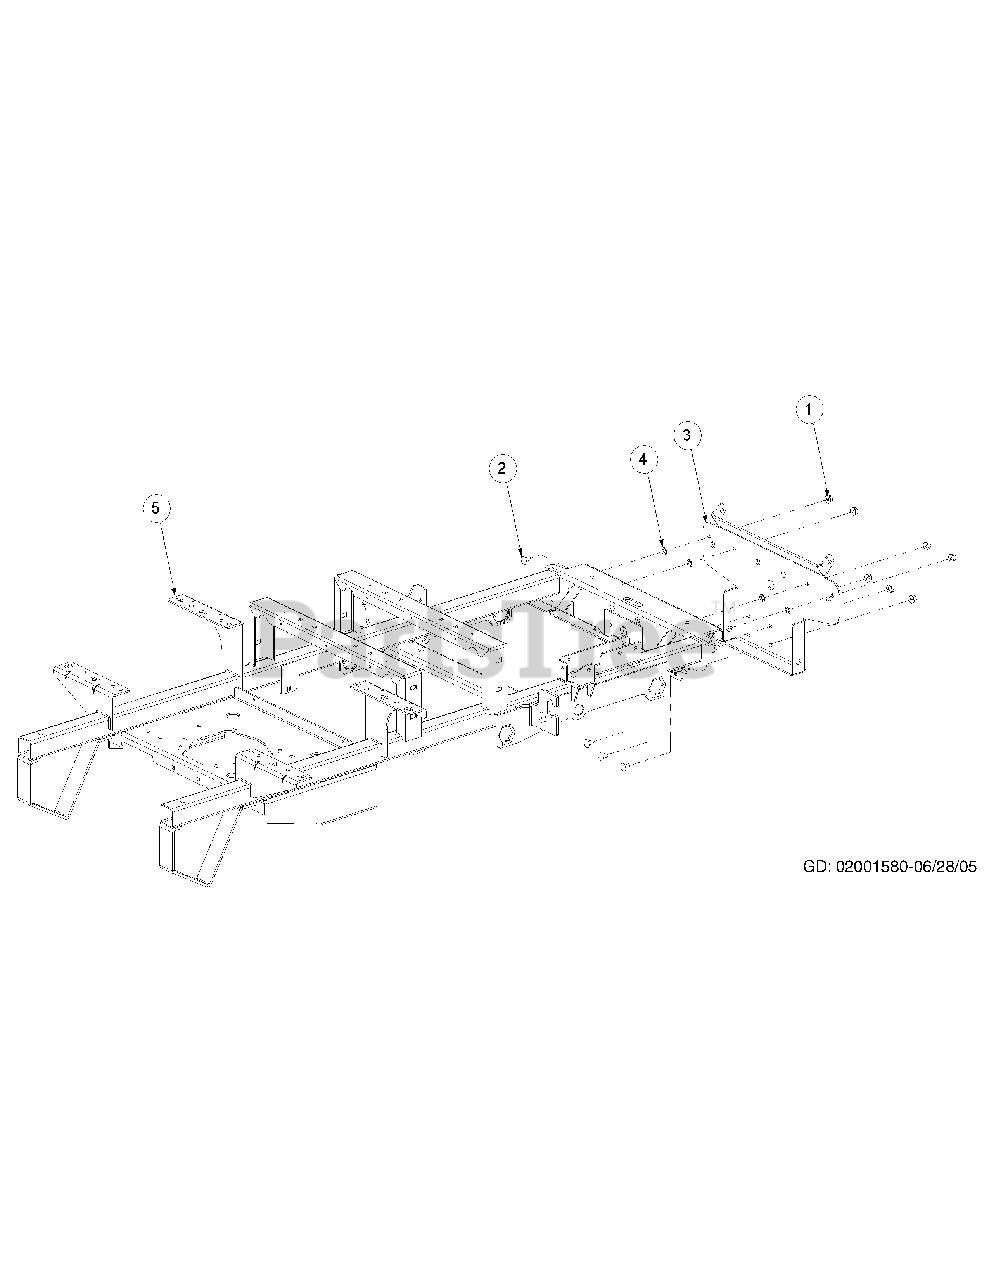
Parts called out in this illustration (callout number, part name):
1	Hex Nut, 3/8-16 Flange Lock
2	Carriage Bolt, 3/8-16 x .75 Long
3	Bracket Assembly, Frame, Front
4	Push Retainer, 3/8"
5	Frame Assembly
